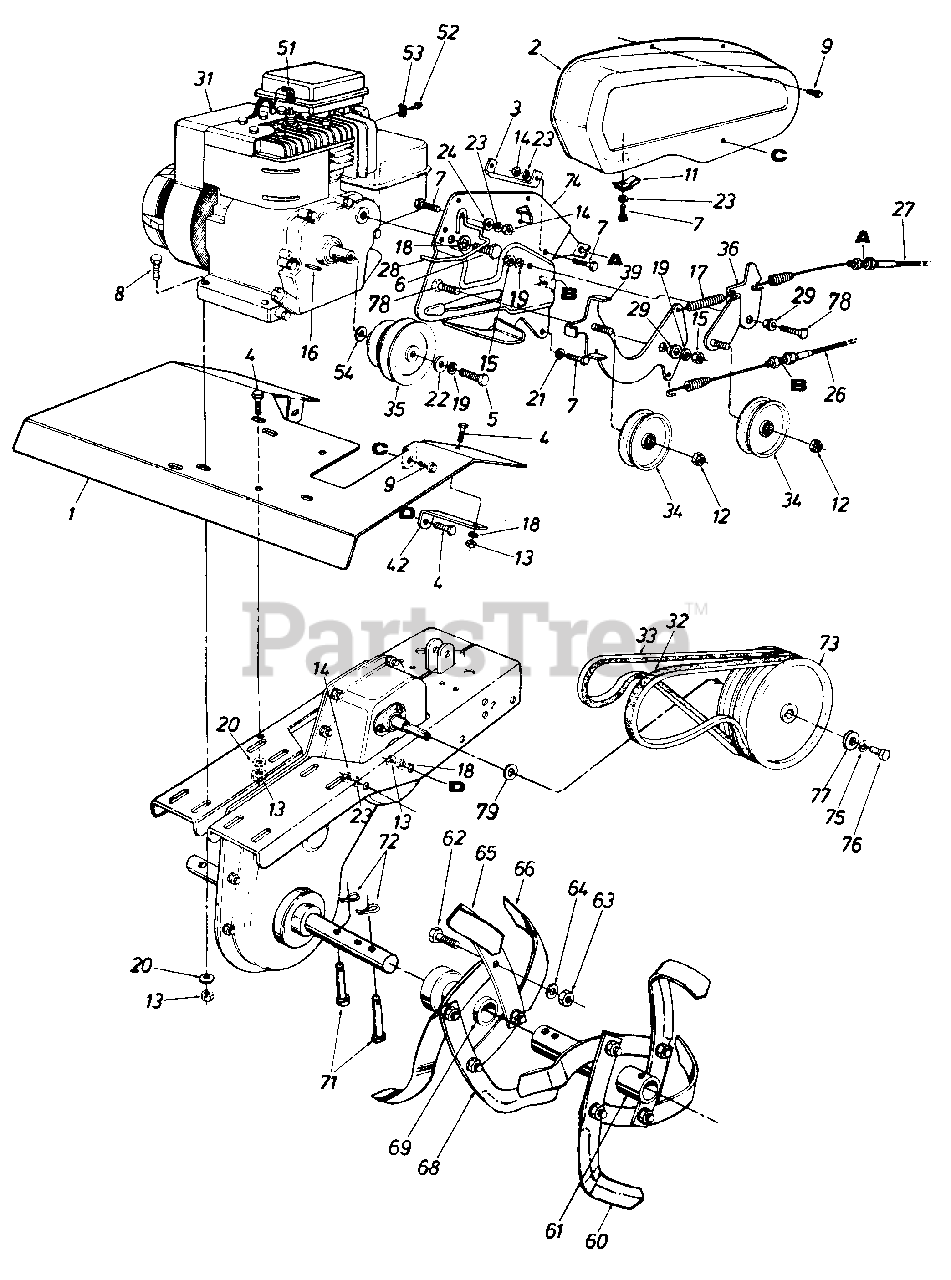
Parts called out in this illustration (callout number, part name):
1	Tine Shield
4	Hex Bolt 5/16-18 x .75" Lg.
5	Hex Bolt 3/8-24 x 1.25" Lg.
6	Hex Bolt 5/16-24 x .62" Lg.
7	Hex Bolt 1/4-20 x .85" Lg.
8	Hex Bolt 5/16-18 x 1.5" Lg.
9	Hex Wash. Hd. Tap Scr. 1/4-20 x .5" Lg.
11	Speed Nut 1/4-20 Thd.
12	Hex L-Nut 3/8-24 Thd.
13	Hex Nut 5/16-18 Thd.
14	Hex Nut 1/4-20 Thd.
15	Hex Nut 3/8-24 Thd.
16	Sq. Key 3/16 x 1.5" Lg.
17	Extension Spring 2.03 Lg.
18	L-Wash. 5/16" I.D.
19	L-Wash. 3/8" I.D.
20	Bell-Wash. 5/16" I.D.
21	Spr. Wash. .265" I.D. x .562" O.D.
22	Fl-Wash. 3/8" I.D. x 1" O.D. x 1.27"
23	L-Wash. 1/4" I.D.
24	Fl-Wash. .25 I.D. x .62 O.D.
26	Clutch Control Cable
27	Clutch Control Cable
28	Belt Guard Rod
29	Shld. Spacer .380 I.D.
32	V-Belt
33	V-Belt
34	Fl-ldler w/Flanges 3.12 O.D. x .75
35	Engine Pulley
52	Hex Sems Scr. #10-32 x .62" Lg.
53	Casing Clamp
54	Fl-Wash. .75" I.D. x 1.375" O.D.
60	Outer Tine Ass'y. Comp. L.H.
61	Outer Tine Adapter Ass'y.
62	Hex Bolt 3/8-24 x 1.25" Lg.
63	Hex Nut 3/8-24 Thd.
64	L-Wash. 3/8" I.D.
69	Inner Tine Adapter Ass'y.
71	Clevis Pin
72	Intern. Coter Pin
73	Transmission Pulley 6" Dia.
74	Clutch Mtg. Plate Ass'y.
75	L-Wash. 5/16" I.D.
76	Patch Bolt 5/16-18 x 1" Lg.
77	Fl-Wash. 5/16 I.D.
78	Hex Bolt 3/8-24 x 1.0" Lg.(Grade 5)
79	Fl-Wash. .635" I.D. x 1.25" O.D.
